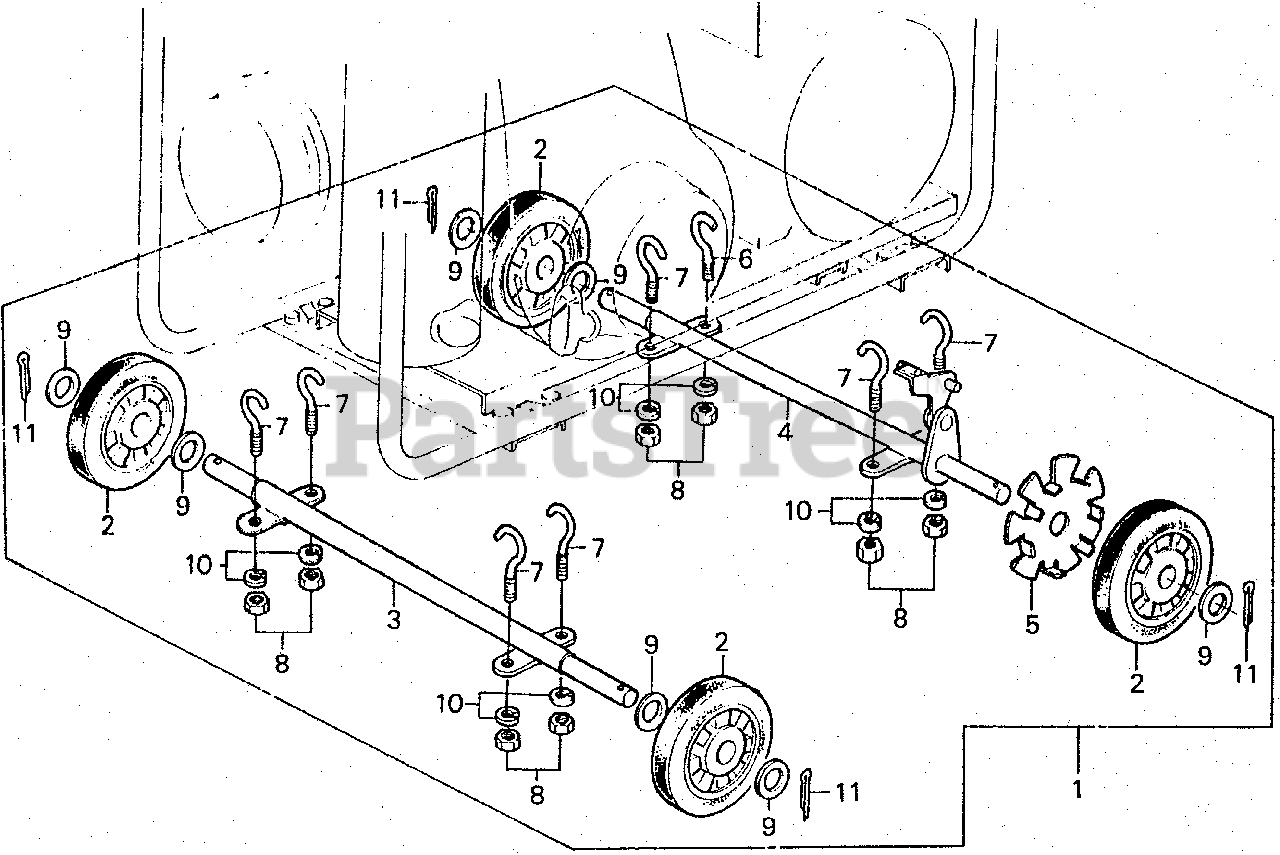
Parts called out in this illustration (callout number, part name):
2	WHEEL
3	SHAFT A, WHEEL
4	SHAFT B, WHEEL
5	PLATE, LOCK
6	BOLT A, HOOK Use up to Frame SN 1114839.
6	BOLT B, HOOK Use from Frame SN 1114840.
7	BOLT B, HOOK
8	NUT, HEX. (8MM)
9	WASHER, PLAIN (20MM)
10	WASHER, SPRING (8MM)
11	PIN, SPLIT (4.0X28)
11	PIN, SPLIT (4.0X30)
